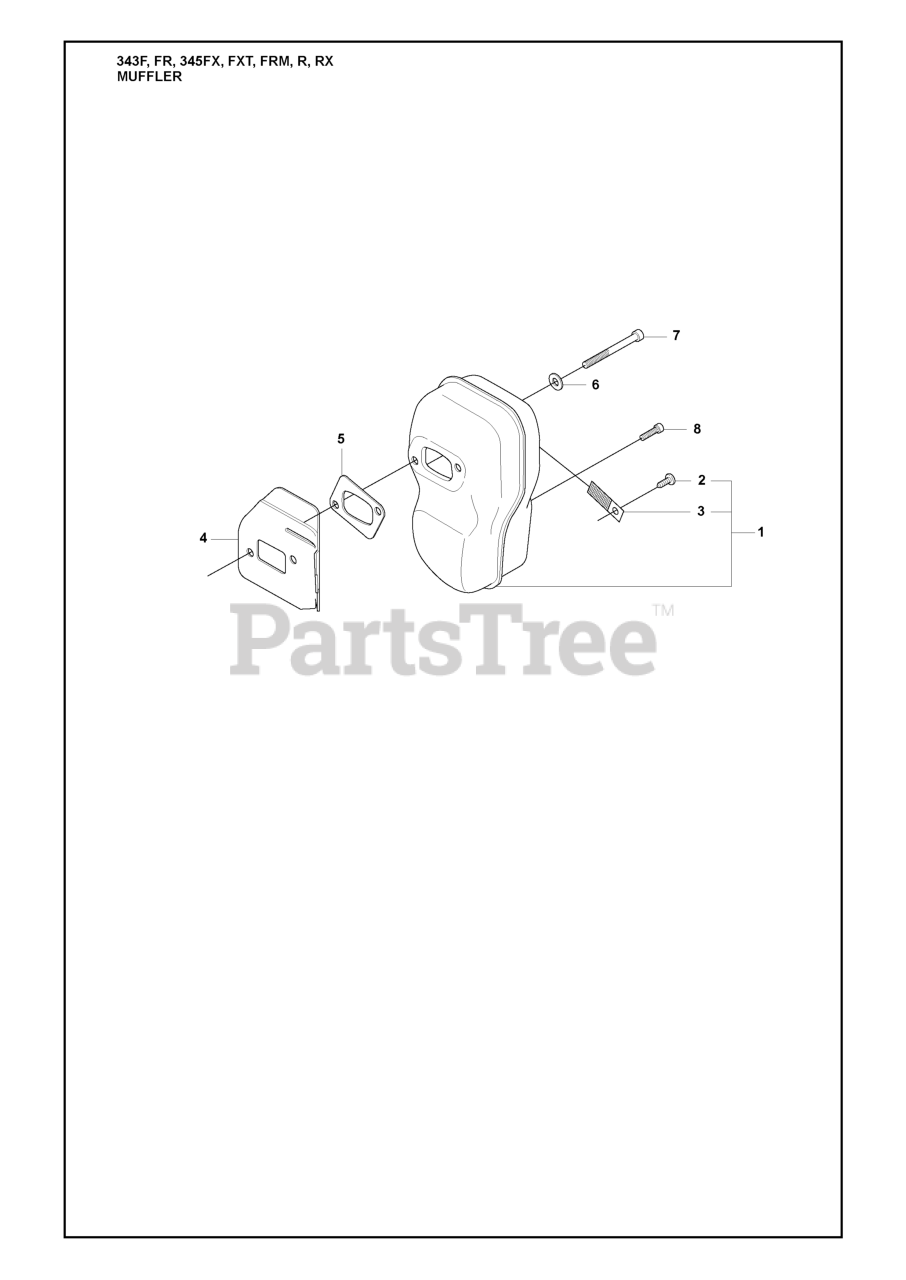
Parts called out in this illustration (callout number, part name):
1	MUFFLER
4	SCREW IHSCFM
6	DOUBLE WASHER
